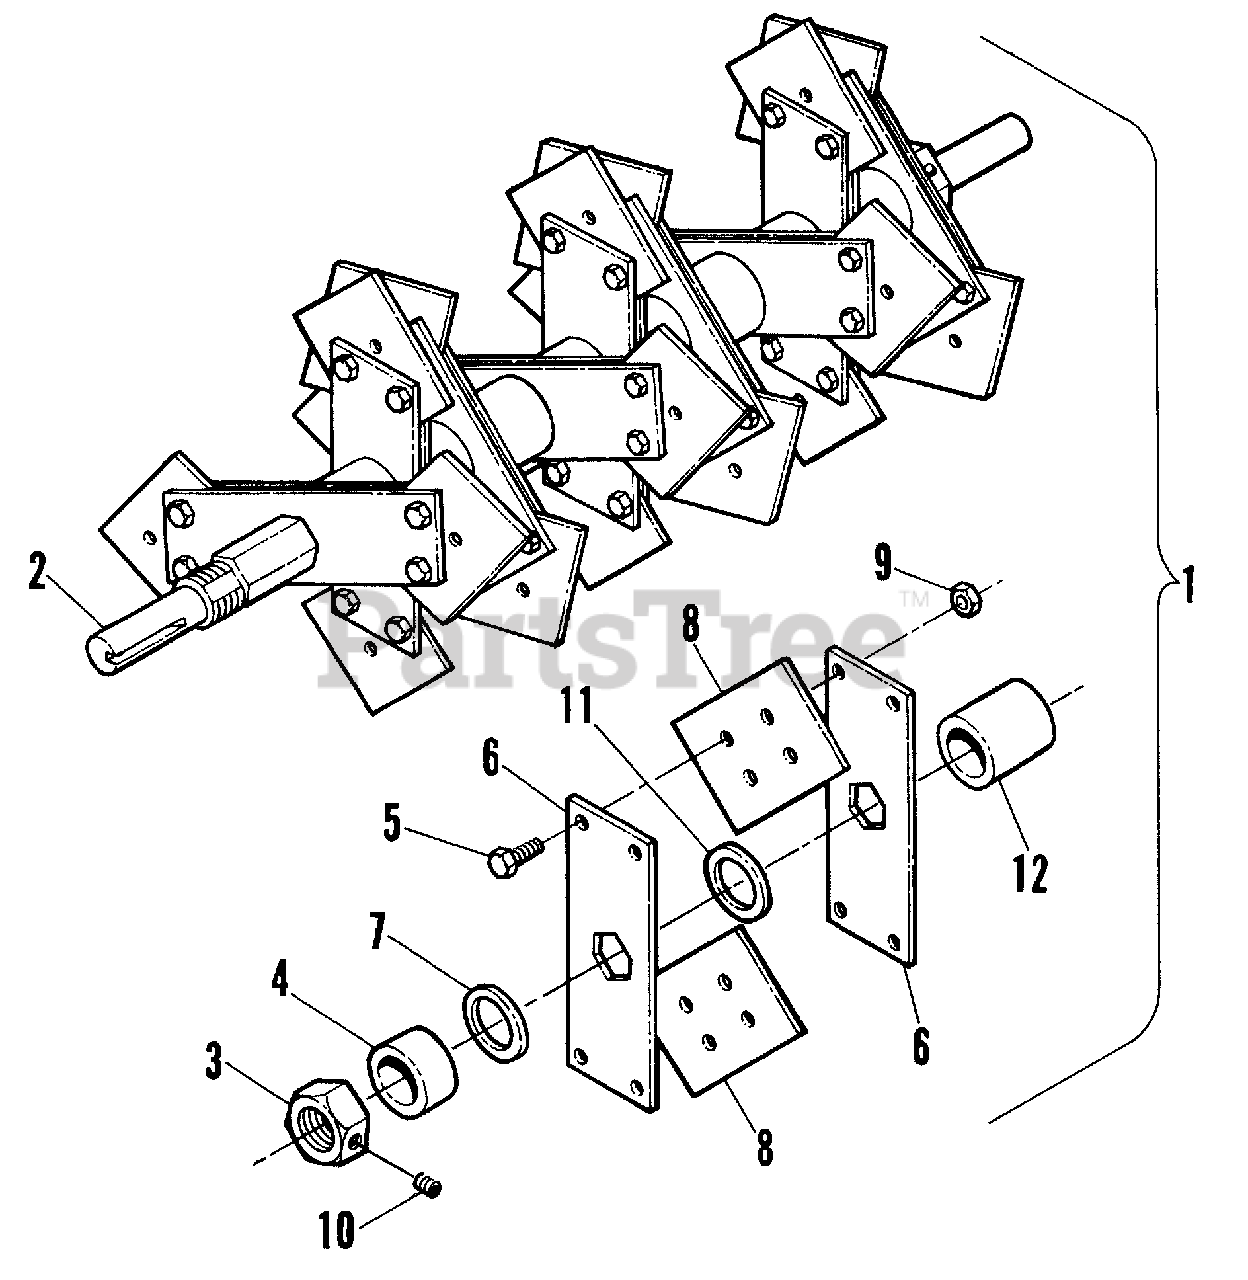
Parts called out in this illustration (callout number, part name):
1	SLICER ASSEMBLY, Complete
2	BARE "SLICER" REEL SHAFT
3	NUT, 1" SAE Jam w/Set Screw
4	SPACER, Sleeve
5	SCREW, 1/4-20 x 5/8" Hex Head Cap, Grade 5
6	HOLDER PLATE
7	WASHER, Flat
8	SLICER BLADE
9	NUT, 1/4-20 Hex Nyloc
10	SCREW, 5/16-18 x 3/8" Socket Head Set
11	BLADE SPACER-WASHER
12	SLEEVE SPACER
